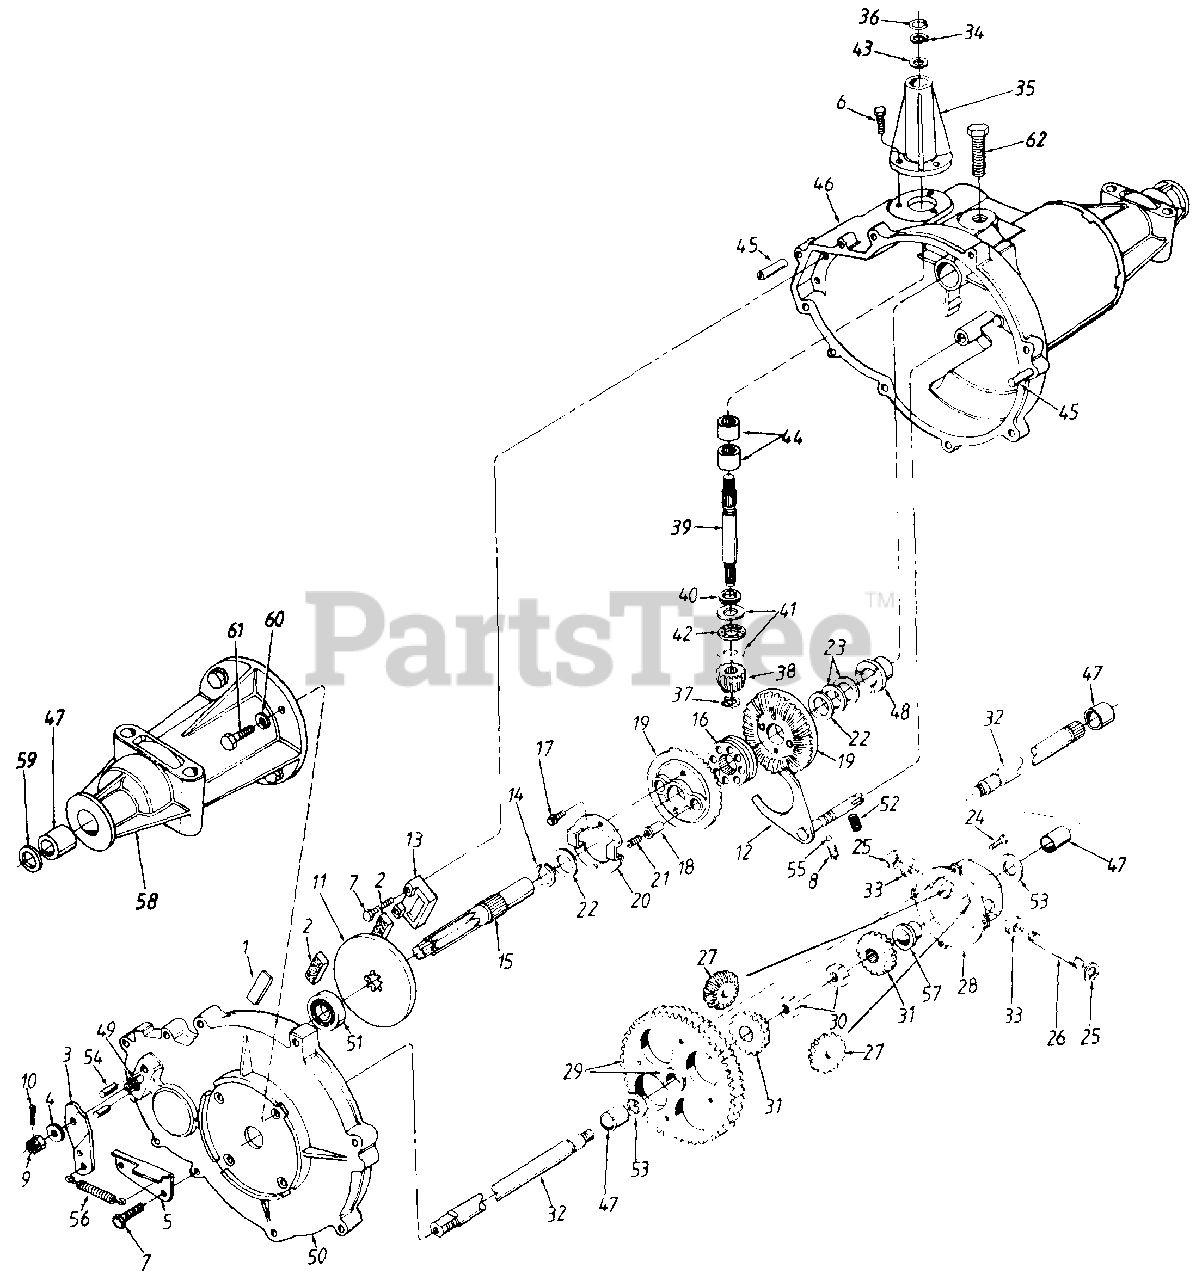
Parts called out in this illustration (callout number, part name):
1	Puck Plate
2	Brake Puck
3	Actuating Arm
4	Fl-Wash. 11/32" I.D. x 7/8" O.D.
5	Brake Stop Brkt.
6	Hex Bolt 1/4-20 x .62" Lg.
7	Hex Tap Scr. 1/4-20 x 1.25" Lg.
8	Spring Detent
9	Castle Nut 5/16-24 Thd.
10	Cotter Pin 3/32" Dia. x 1" Lg.
11	Brake Disc
12	Shifter Ass'y.
13	Brake Puck Holder
14	Retaining Ring
15	Shaft Drive
16	Shift Collar
17	Hex Wash. Hd. Tap Scr. 1/4-20 x .38" Lg.
18	Drive Pin
19	Bevel Gear Ass'y.
20	Spring Retaining Plate
21	Drive Spring
22	Fl-Wash. .915" I.D. x 1.5" O.D.
23	Fl-Wash. .915" I.D. x 1.37" O.D.
24	Pan Hd. Scr. 1/4-20 x .5" Lg.
25	Snap Ring
26	Cross Shaft
27	Miter Gear 15T
28	Differential Can Assembly
29	Differential Gear Ass'y. w/Bearing
30	Hex Ins. L-Nut 1/2-20 Thd.
31	Miter Gear
33	Differential Thrust Spacer
34	Retainer Ring
35	Input Bearing Housing
36	Wire Ring
37	Retaining Ring
38	Pinion Input 14T
39	Input Shaft
40	Seal 5/8" I.D.
41	Thrust Wash. .621" I.D. x 1.12"
42	Thrust Bearing
43	Fl-Wash. 5/8" I.D. x 1.25" O.D.
44	Needle Brg. 5/8" x 1/2" Lg.
45	Dowel Pin
46	R.H. Housing
47	Sleeve Bearing 3/4" I.D.
48	Flange Bearing .906" I.D.
49	Sq. Head Bolt 5/16-24 Thd.
50	L.H. Housing
51	Ball Bearing .669" I.D.
52	Set Screw 5/16-18 x 3/8" Lg.
53	Fl-Wash. .76" I.D. x 1.5" O.D.
54	Brake Actuating Pin
55	Ball Detent
56	Ext. Spring 1.14" Lg.
57	Differential Flange Brg.
58	Axle Horn Ass'y.
59	Oil Seal 3/4" I.D.
60	L-Wash. 3/8" I.D. (H.D.)
61	Hex Bolt 3/8-24 x 1.25" Lg.
62	Nylon Hex Cap Scr. 1/2-13 x .75" Lg.
